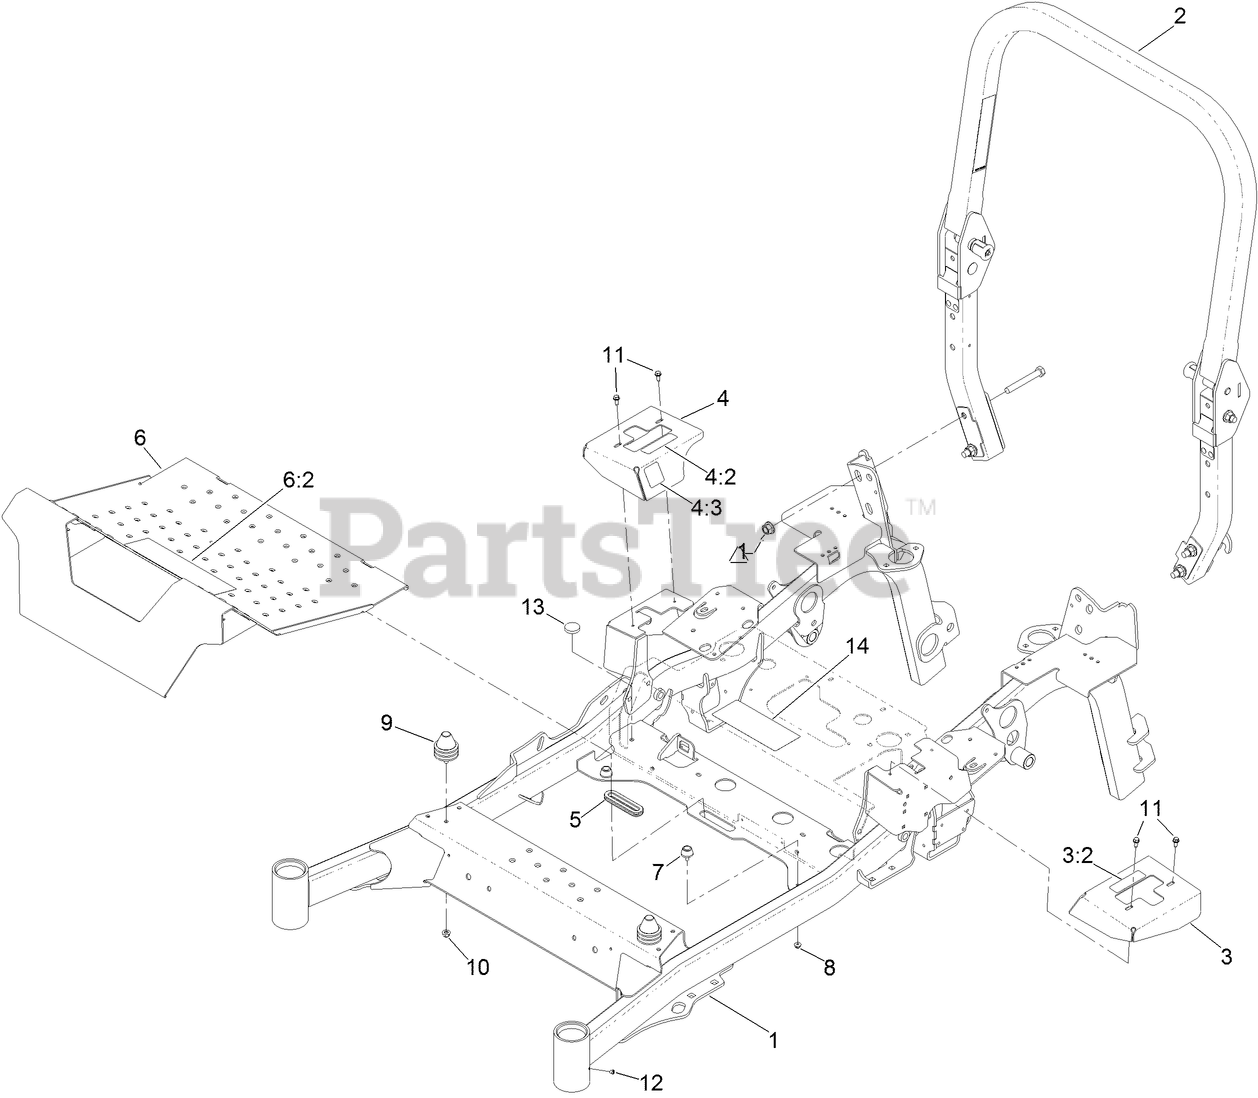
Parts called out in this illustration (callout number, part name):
1	MAINFRAME ASM, RD
2	ASM, ROPS-7500D DIESEL
3	COVER-MOTION CONTROL, LH
3:2	DECAL-CONTROL, MOTION
4	COVER-MOTION CONTROL, RH
4:2	DECAL-CONTROL, MOTION
4:3	DECAL-PARK BRAKE, CE
5	GROMMET-RUBBER
6	PAN-FLOOR
6:2	DECAL-DANGER
7	BUMPER-RUBBER
8	NUT-HF
9	ISOLATOR
10	NUT-HF, NI
11	SCREW-HWH
13	BUMPER-PUSH-IN, RUBBER
14	DECAL-SERVICE AID
